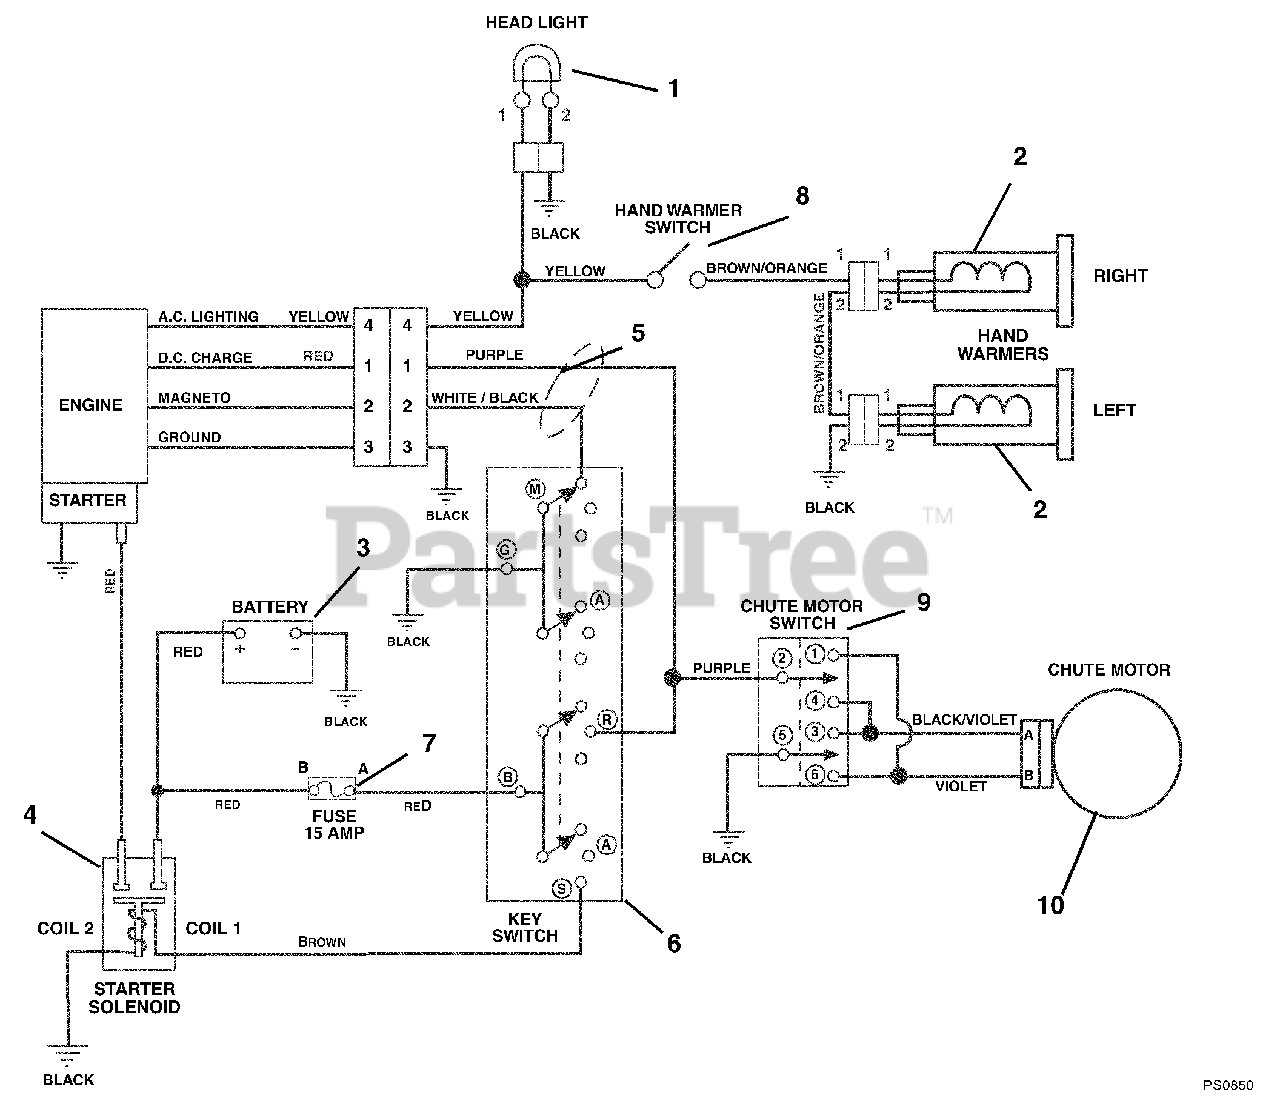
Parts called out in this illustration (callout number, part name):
1	HEADLAMP, OVAL W/ 1156 BULB
2	WARMER, HAND W/TERMINAL
4	SOLENOID
5	HARNESS, WIRE-LT,HW,12V,CHUTE
6	SWITCH ASSEMBLY
7	FUSE, 15 AMP.
8	SWITCH, ON/OFF
9	SWITCH, CHUTE ROTATION
10	MOTOR, ELECTRIC R.H. - CHUTE
